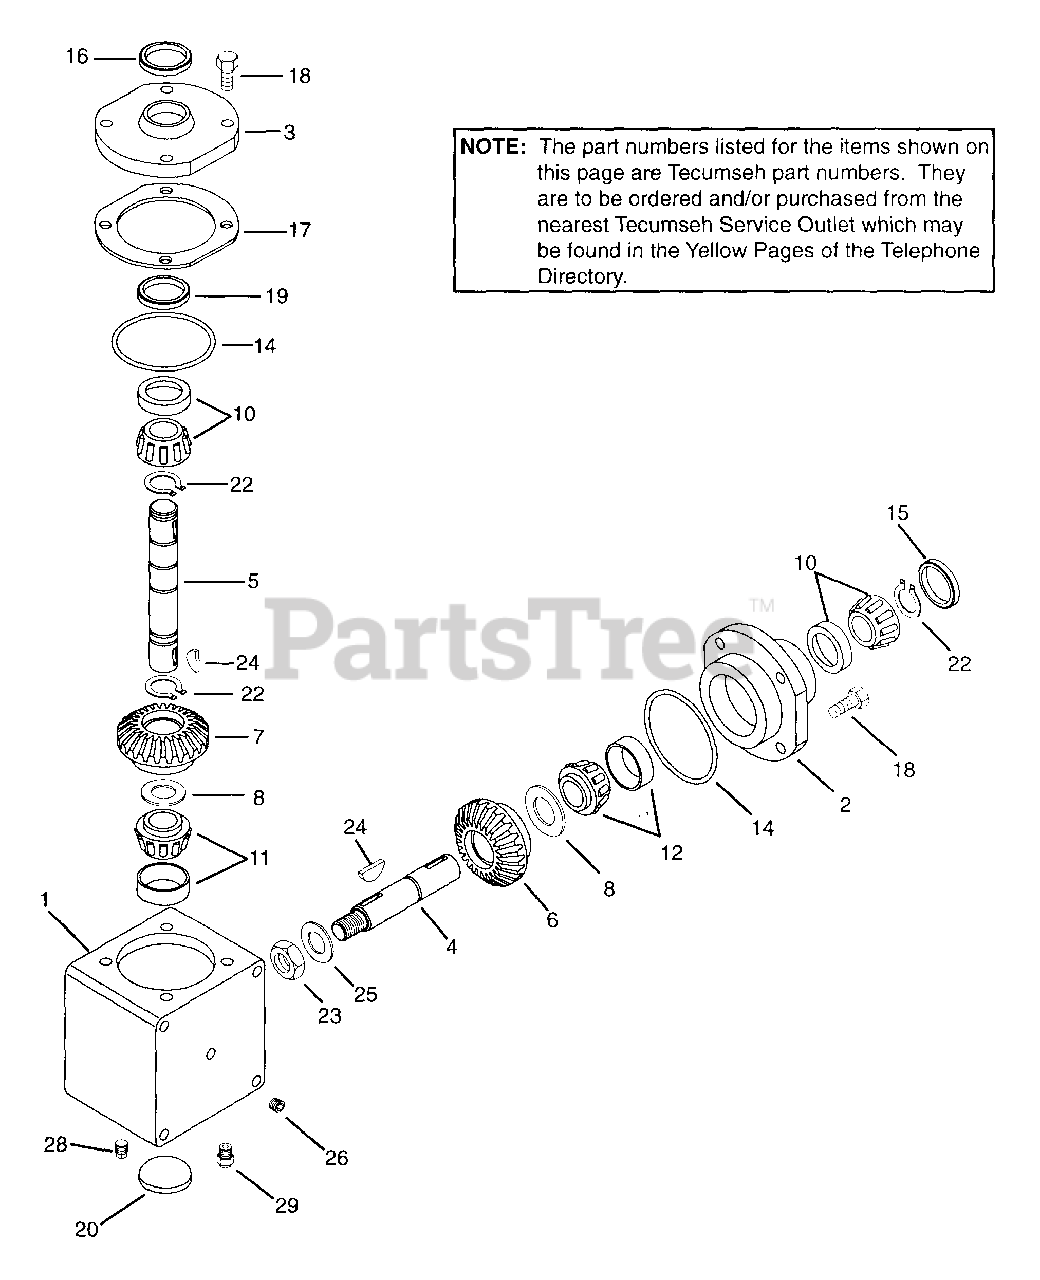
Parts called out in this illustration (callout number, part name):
1	Housing, Right Angle Drive
2	Cap, Retainer
3	Cap, Retainer
4	Shaft, Input (5.38" long)
5	Shaft, Output (7.89" long)
6	Gear, Spiral Bevel (25 teeth)
7	Gear, Spiral Bevel (26 teeth)
8	Shim (1-1/2" O.D. x 1-1/64" I.D. x .002 thick)
9	Shim (2.000" O.D. x 1.531" I.D. x .002 thick)
10	Bearing & Cup Assembly.
11	Bearing & Cup Assembly.
12	Bearing & Cup Assembly.
14	"O" Ring
15	Seal, Oil
16	Seal, Oil
17	Shim, Cap Retainer
18	Screw, Hex, HD. Sems, 5/16-18 x 1
19	Ring Load
22	Ring, Retaining
23	Jam, Nut 3/4-16
24	Key, Woodruff
25	Washer, Flat 1
26	Plug, Pipe 14-18
28	Plug, Pipe 1/8-27
29	Valve, Relief
